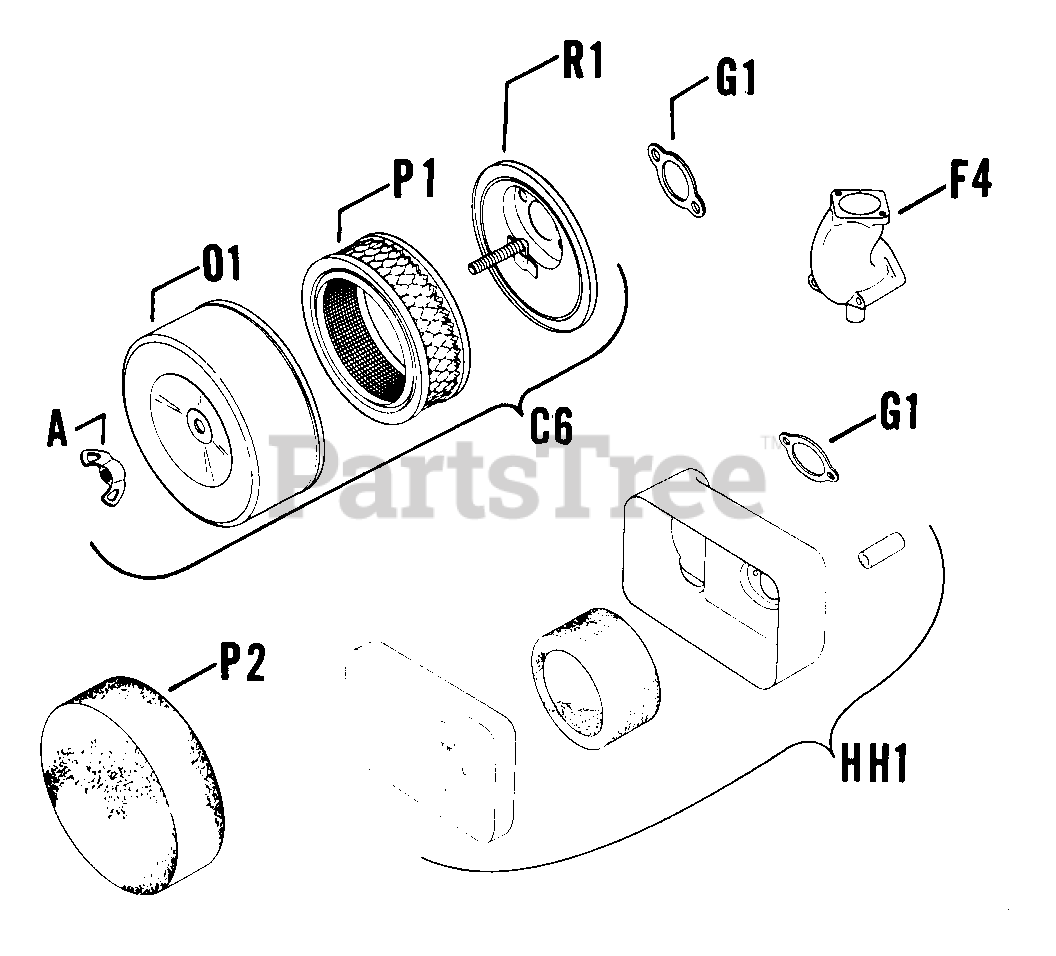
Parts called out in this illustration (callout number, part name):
A	NUT, WING 1/4-20 USE 25 100 15-S
C6	CLEANER
G1	GASKET - USE 41 041 11
O1	COVER, AIR CLEANER
P1	FILTER DISCONTINUED
R1	BASE, AIR CLEANER - DISCONTINUED
